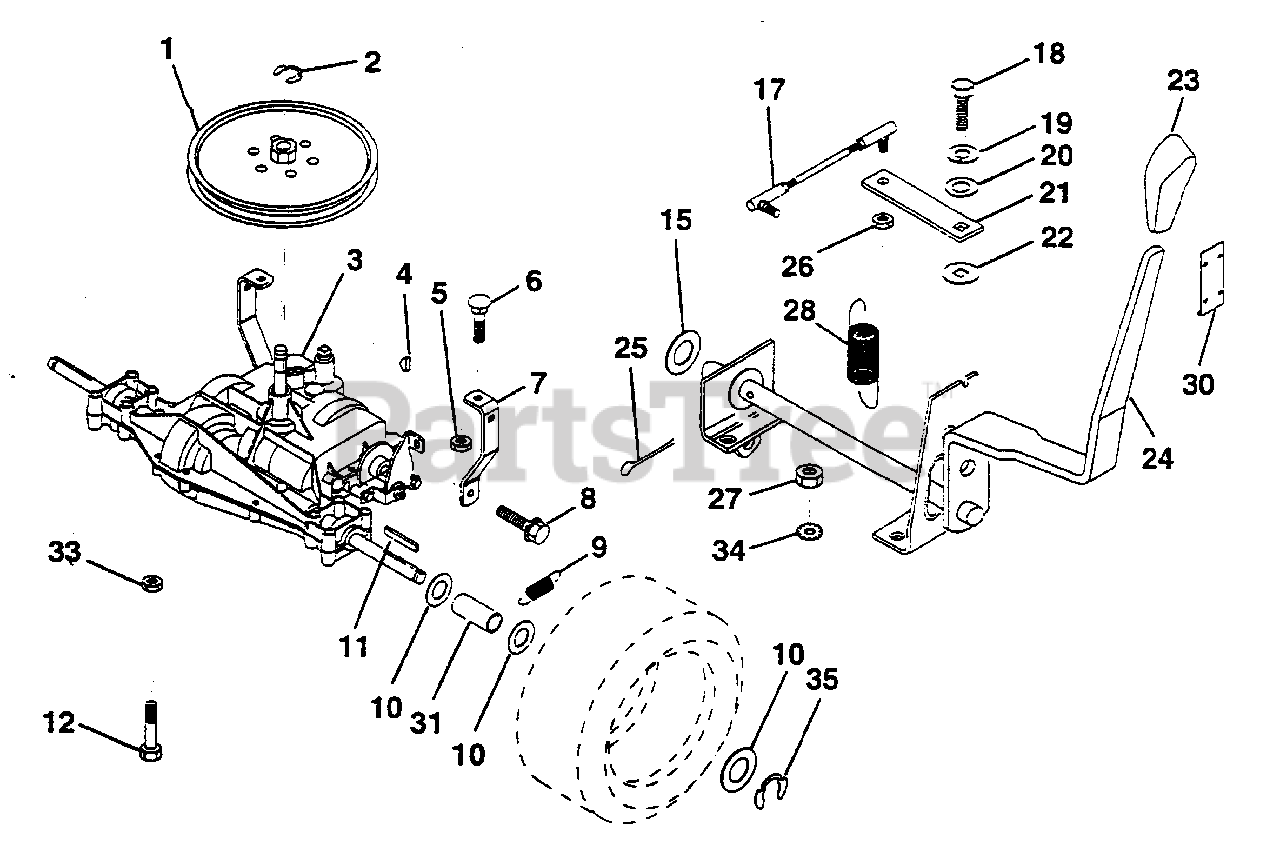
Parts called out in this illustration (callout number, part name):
1	Pulley (AYP part number)
2	Ring, Retainer (AYP part number)
4	Key, Woodruff #9 (AYP part number)
5	Nut, Crownlock 5/16-18
6	Bolt, Carriage 5/16-18 UNC x 3/4
7	Strap, Torque (AYP part number)
8	Screw 5/16-18 x 3/4
9	Spring, Brake (AYP part number)
10	Washer 25/32 x 1-1/4 x 16 Gauge (AYP part number)
11	Key, Square (AYP part number)
12	Bolt, Hex Head, Fin. 3/8-16 x 2-3/4 (AYP part number)
15	Washer 17/32 x 1 x 16 Gauge (AYP part number)
17	Link, Shift (AYP part number)
18	Bolt, Hex Head, Fin. 1/4-28 UNF x 3/4 Grade 8 (AYP part number)
19	Washer, Lock 1/4 (AYP part number)
20	Washer 9/32 x 3/4 x 10 Gauge (AYP part number)
21	Arm, Shift (AYP part number)
22	Washer, Shift Plate (AYP part number)
23	Knob, Round (AYP part number)
24	Handle Assembly, Shift
25	Pin, Cotter 1/8 x 1 (AYP part number)
26	Nut, Hex, Nylon 5/16-24 UNF (AYP part number)
27	Nut, Hex, Keps 5/16-18 (AYP part number)
28	Spring, Extension (AYP part number)
30	Retainer, Spring (AYP part number)
31	Spacer, Split (AYP part number)
33	Nut, Crownlock 3/8-16
34	Washer, Lock, External Tooth 5/16 (AYP part number)
35	E-Ring (AYP part number)
